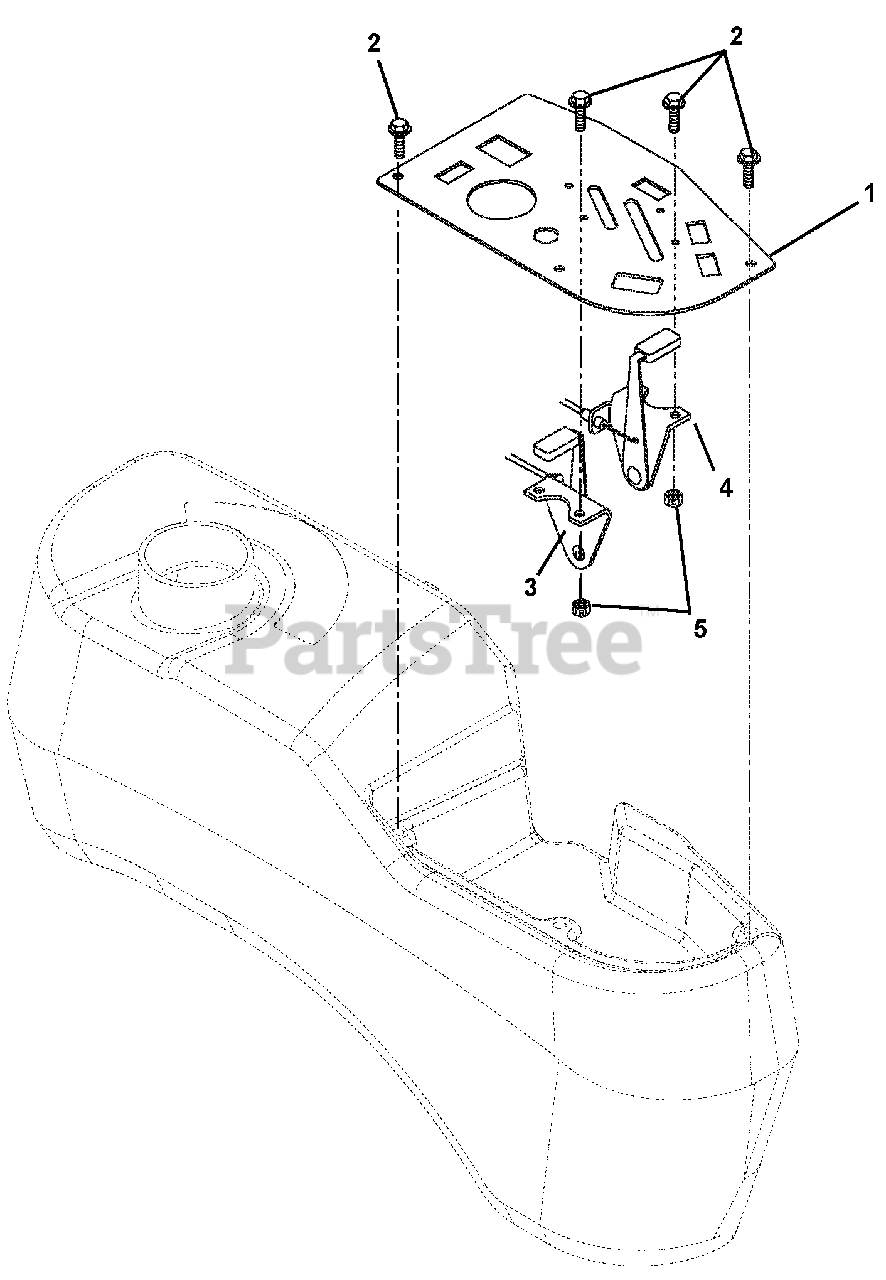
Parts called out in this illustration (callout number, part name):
1	Panel, Control
2	Screw, Machine 10-24 x .50 Hex Washer Head (066, 067, 068, 070, 071, 072)
3	Throttle, Control
4	Choke Control (066, 067, 070)
5	Nut, Locking Nylon 10-24 With Insert (066, 067, 068, 070, 071, 072)
